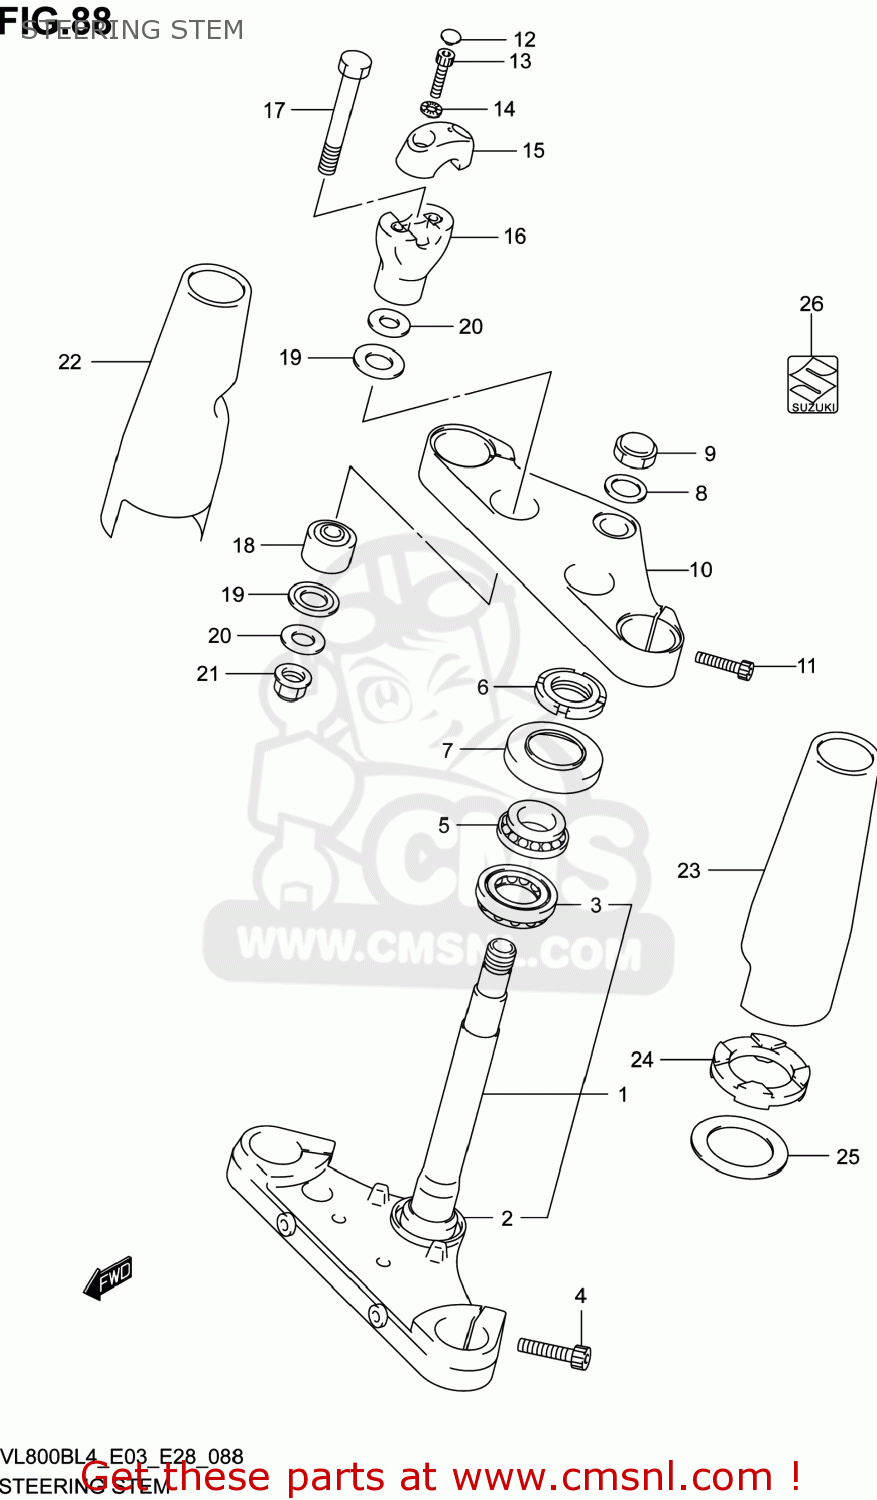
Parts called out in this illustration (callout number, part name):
1	STEM,STEERING
2	SEAL,STEERING LWR
3	BEARING(30X55X17)
4	BOLT
5	BEARING(25X47X15)
6	NUT,STEERING STEM(25X44X10)
7	DUST SEAL,STEERING UPR
8	WASHER(22.5X32X1.6)
9	NUT,CAP
10	HEAD,STEERING STEM
11	BOLT
12	CAP(OD:11)
13	BOLT,HANDLE HOLDER
14	WASHER
15	HOLDER,HANDLE UPR
16	HOLDER,HANDLE UNDER
17	BOLT
18	DAMPER,RUBBER
19	SEAT,RUBBER
20	WASHER
21	NUT
22	COVER,UPPER,R
23	COVER,UPPER,L
24	SEAT,RUBBER
25	WASHER
26	EMBLEM,S
